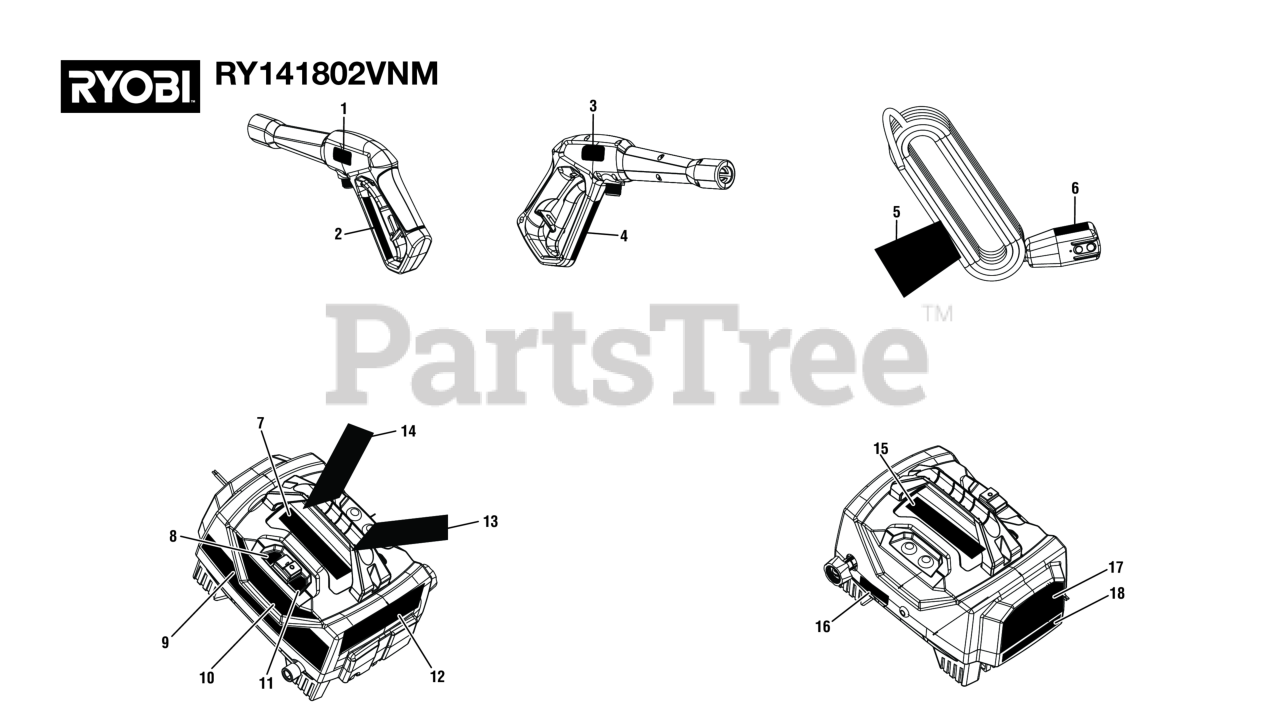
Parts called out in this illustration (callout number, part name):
1	Trigger Handle Warning Label (English)
2	Trigger Handle Warning Label (French/Spanish)
3	Trigger Handle Label (Logo Label)
4	Trigger Handle Data Label
5	Warning Label (Cord Wrap)
6	Power Cord Label
7	Quick Start Label
8	Off Label
9	Performance Label
10	Ryobi Label
12	Performance Label
13	Danger Hangtag (Spanish)
14	Nozzle Hangtag
15	Nozzle Selection Label
16	Inquires Label (Ryobi)
17	Regulator Label
18	Data Label
